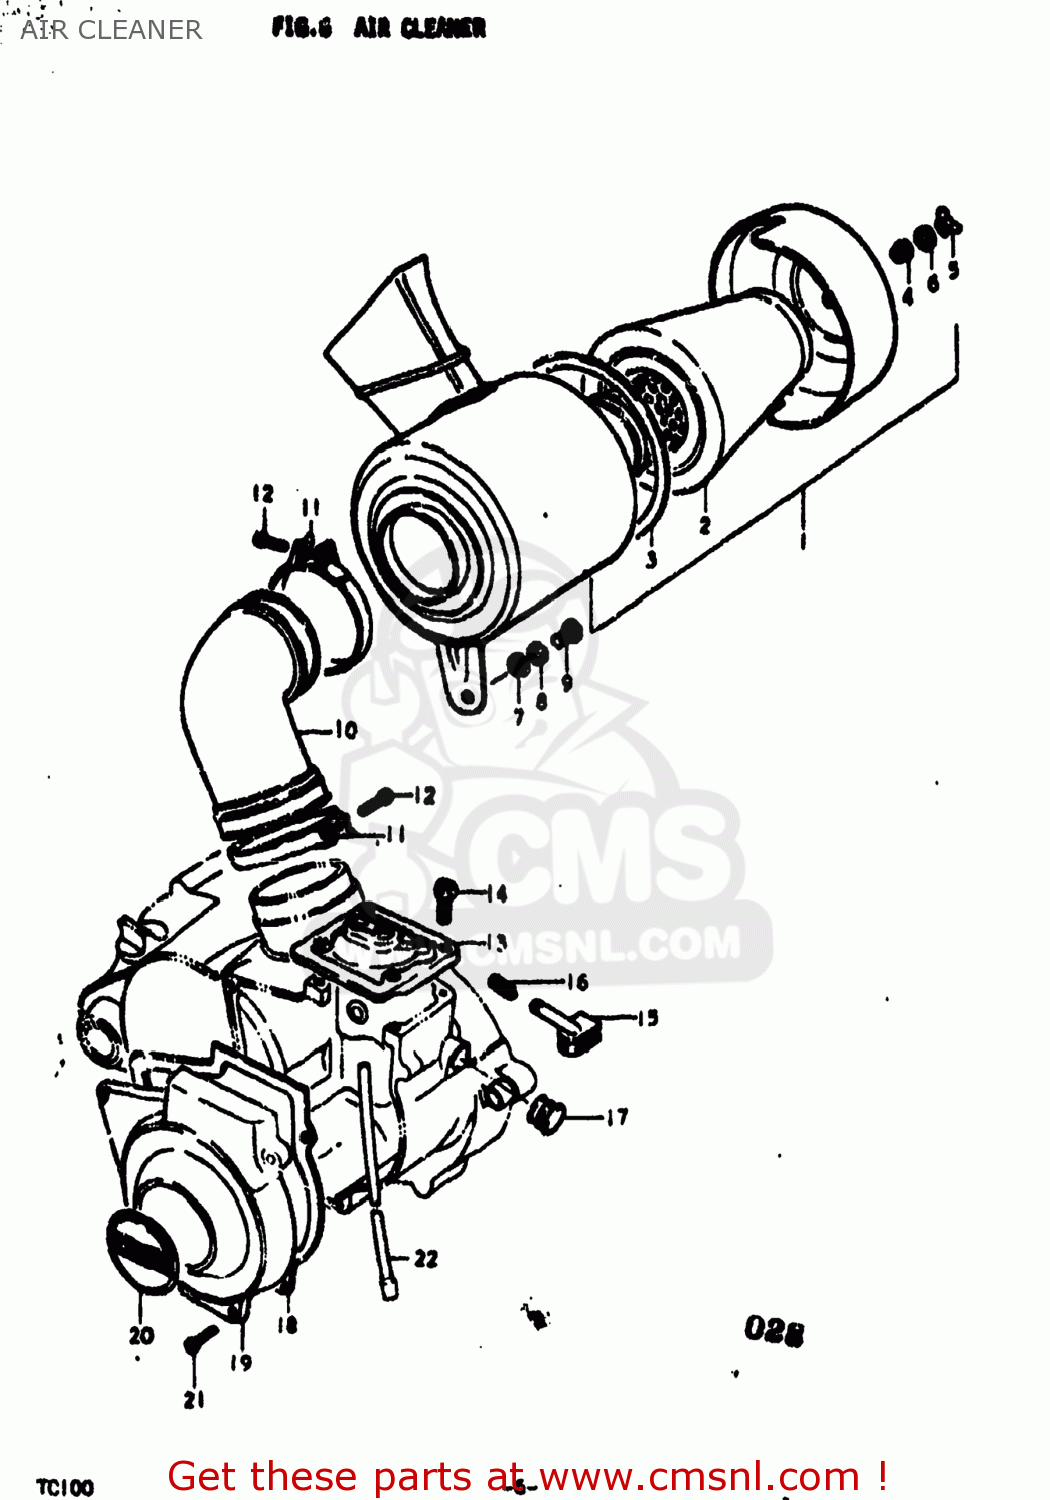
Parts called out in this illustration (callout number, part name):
1	CLEANER ASSEMBLY,AIR
2	FILTER ASSY,AIR CLEANER
4	GASKET
5	NUT
6	HOLDER,FILTER
7	WASHER
8	LOCK WASHER
9	SCREW
10	TUBE,AIR CLEANER OUTLET
11	CLAMP
12	SCREW
13	COVER,CARBURETOR,TOP
14	SCREW
15	GROMMET
16	SPRING
17	Plug
18	GASKET,CARB INSPECTION CAP (NAS)
19	CAP,CARBURETOR INSPECTION
20	EMBLEM,CARB INSPECTION CAP
21	SCREW
22	HOSE
